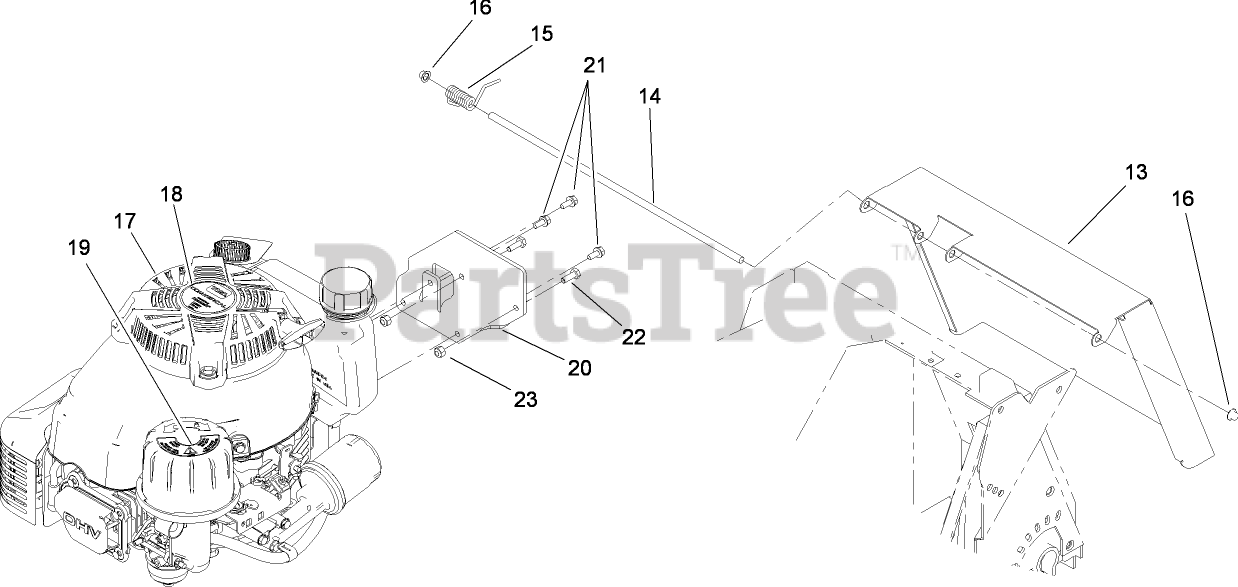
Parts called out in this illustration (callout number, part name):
13	DOOR-DISCHARGE, REAR
14	ROD-DOOR
15	SPRING-TORSION, DOOR
16	PUSHNUT-CAP, WASHER
17	Loose Parts Package
20	BRACKET-ADAPTER, TANK
21	SCREW-HWH
22	SCREW-HH
23	NUT-LOCK, NI
